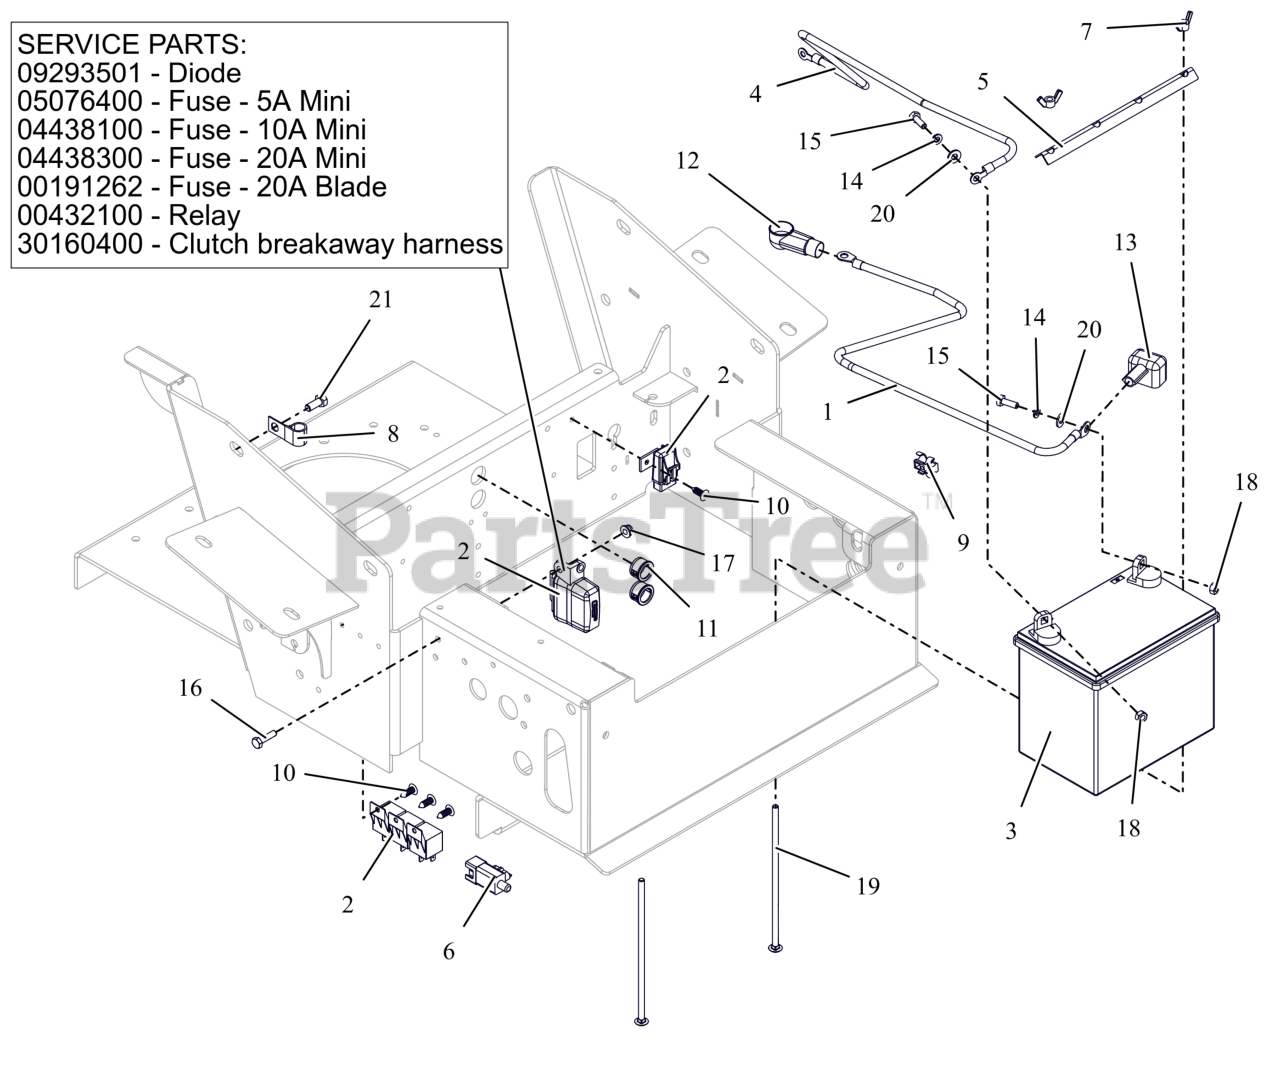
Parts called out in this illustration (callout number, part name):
1	CABLE,POS W/(2) 5/16 RING 30LG
2	HARNESS, PT100 WIRE
2	DIODE, CONNECTOR SHELL
2	FUSE, 5 AMP MINI-ATC
2	FUSE,10 AMP MINI-ATC
2	FUSE,20 AMP MINI ATC
2	FUSE, 20 AMP BLADE S/O
2	RELAY,SEALED W/DIODE
2	HARNESS- PTO CLUTCH JUMPER
3	BATTERY, 300 CCA 10U1L
4	CABLE-NEGATIVE BATTERY 24.00"
5	HOLD DOWN
6	SWITCH, SNAP IN - N.O./N.O.
7	NUT, LK-WING .25-20 ZCC
9	CLIP,T,.31-.38,
10	RIVET, .25 NYLON PANEL
11	BUSH, PANEL SNAP .687X.875X.56
12	BOOT, .65ID POS
13	INSULATOR
14	WSHR,LK-REG .250X.062 ZCC
15	BLT, HEX .25-20X.75 G5 ZCC
16	BLT,HEX .25-20X1.00 G5 ZCC
17	NUT,NYL-FLG .25-20 GF ZCC
18	NUT-STD .250-20 G2 ZCC
19	BTL,RHSN .250-20 X 7.5 G5 ZCC
20	WSHR,FLT .281X.625X.065 ZCC
21	BLT,HEX .31-18X.75 G5 ZCC
